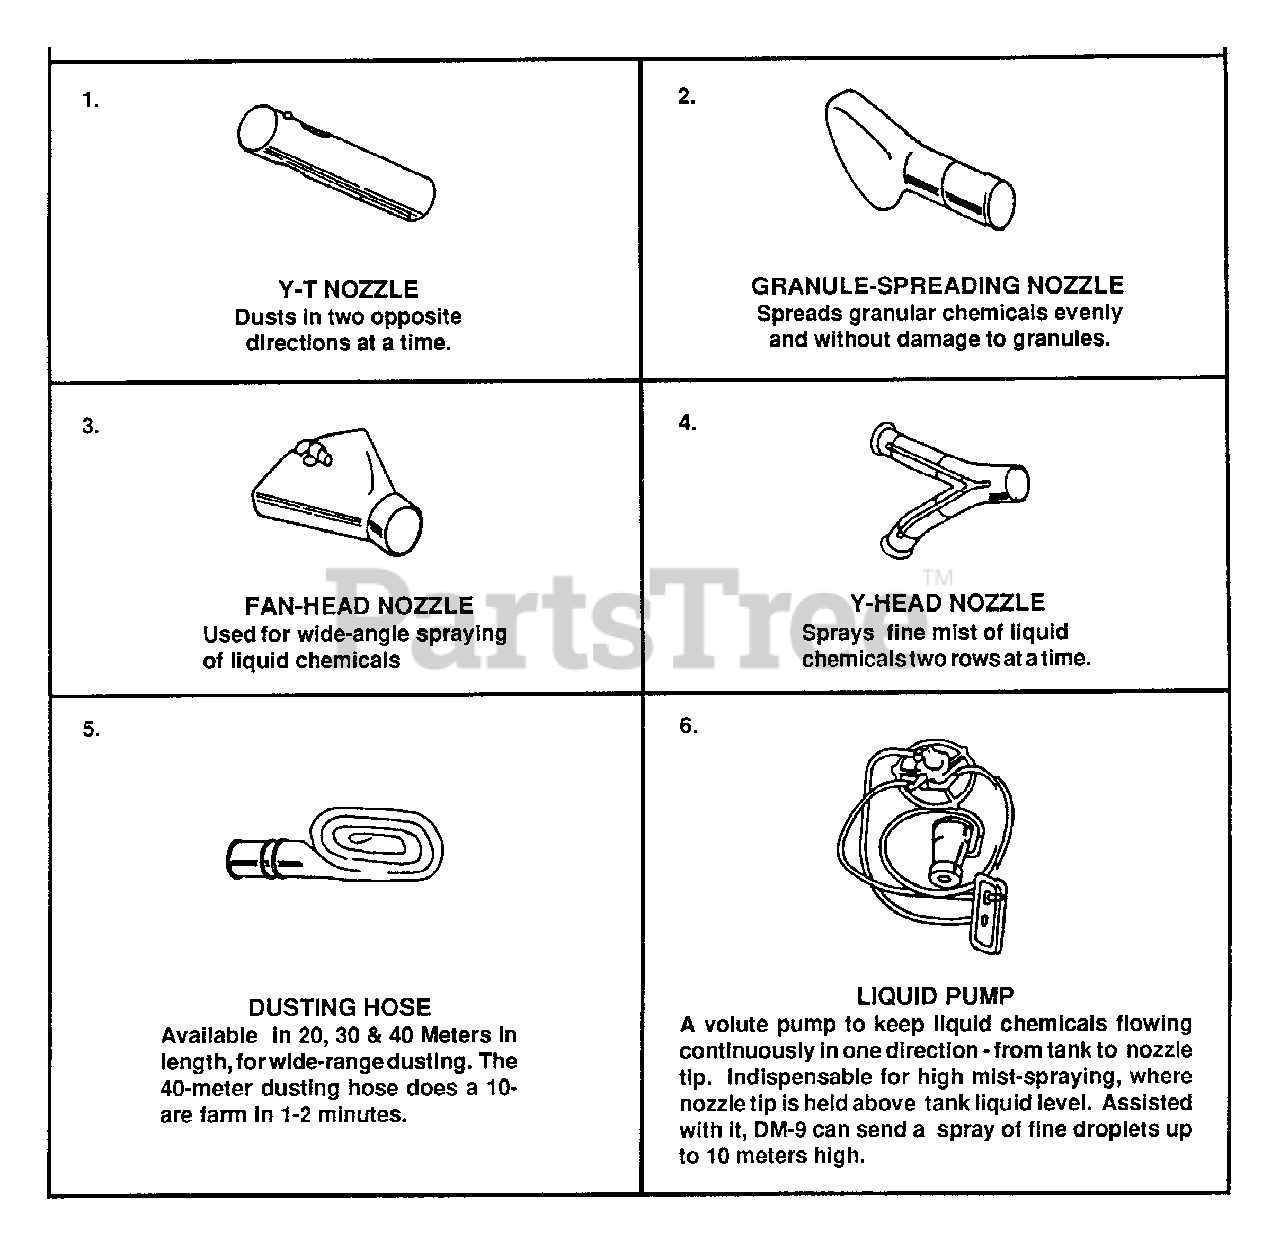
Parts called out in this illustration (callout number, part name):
1	Y-T NOZZLE
2	NOZZLE, GRANULE SPREADING
3	NOZZLE, FAN HEAD
4	NOZZLE ASSY, MISTING
5	DUSTING HOSE - 20M
5	HOSE, DUSTING - 30M
5	DUSTING HOSE - 40M
6	LIQUID PUMP
